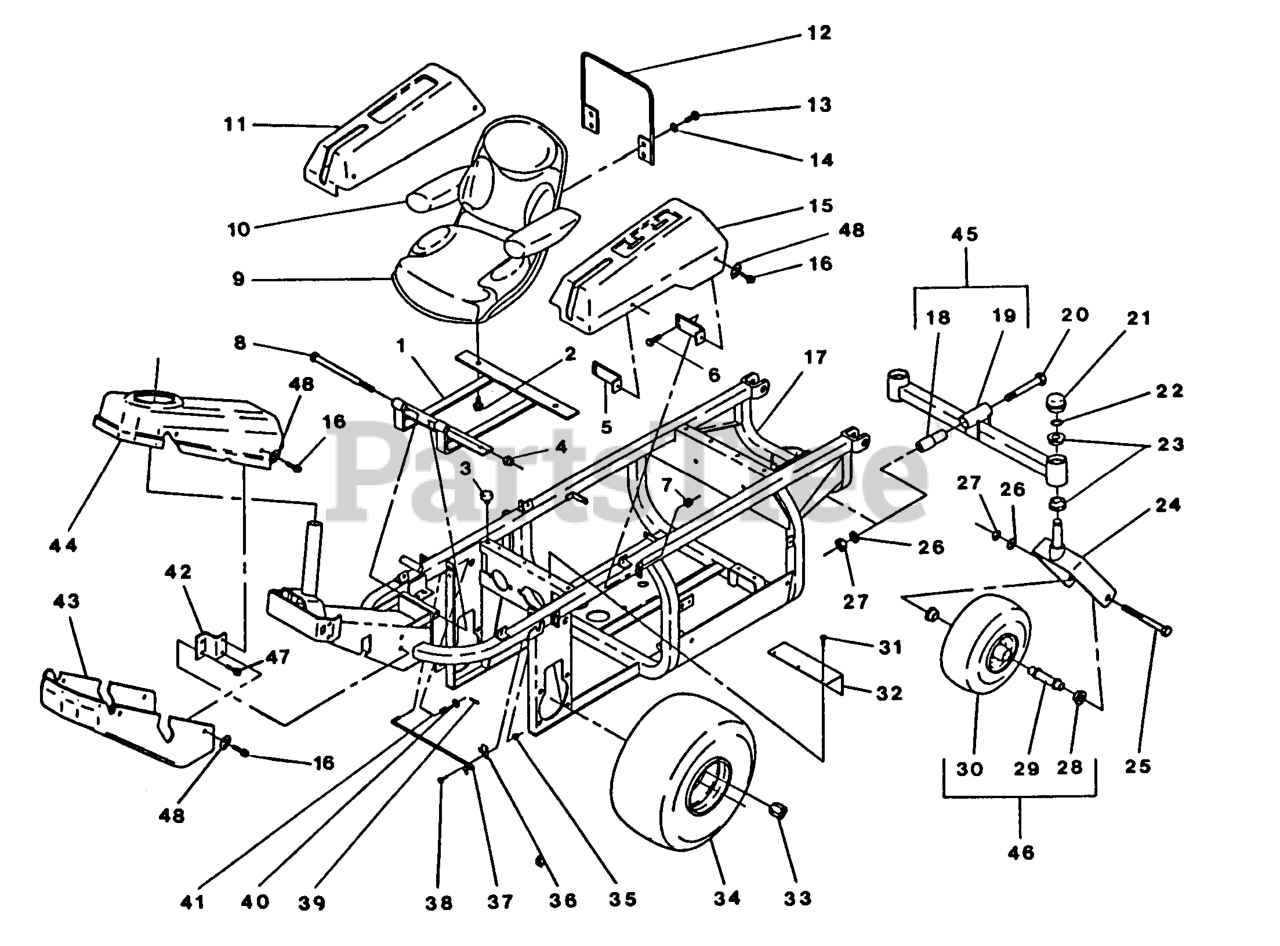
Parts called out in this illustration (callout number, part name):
11	FENDER,RH RANGER
15	FENDER,LH RANGER
21	CAP,GREASE
23	BEARING,FLANGED
29	WLD,WHEEL SPACER
36	CLIP,SEAT HOLDUP ROD
37	ROD,SEAT HOLDUP
41	SPRNG,ST HOLDUP ROD
43	CONSOLE,STEERING BOTTOM
44	CONSOLE,STEERING TOP
46	ASM,CASTER WHEEL
